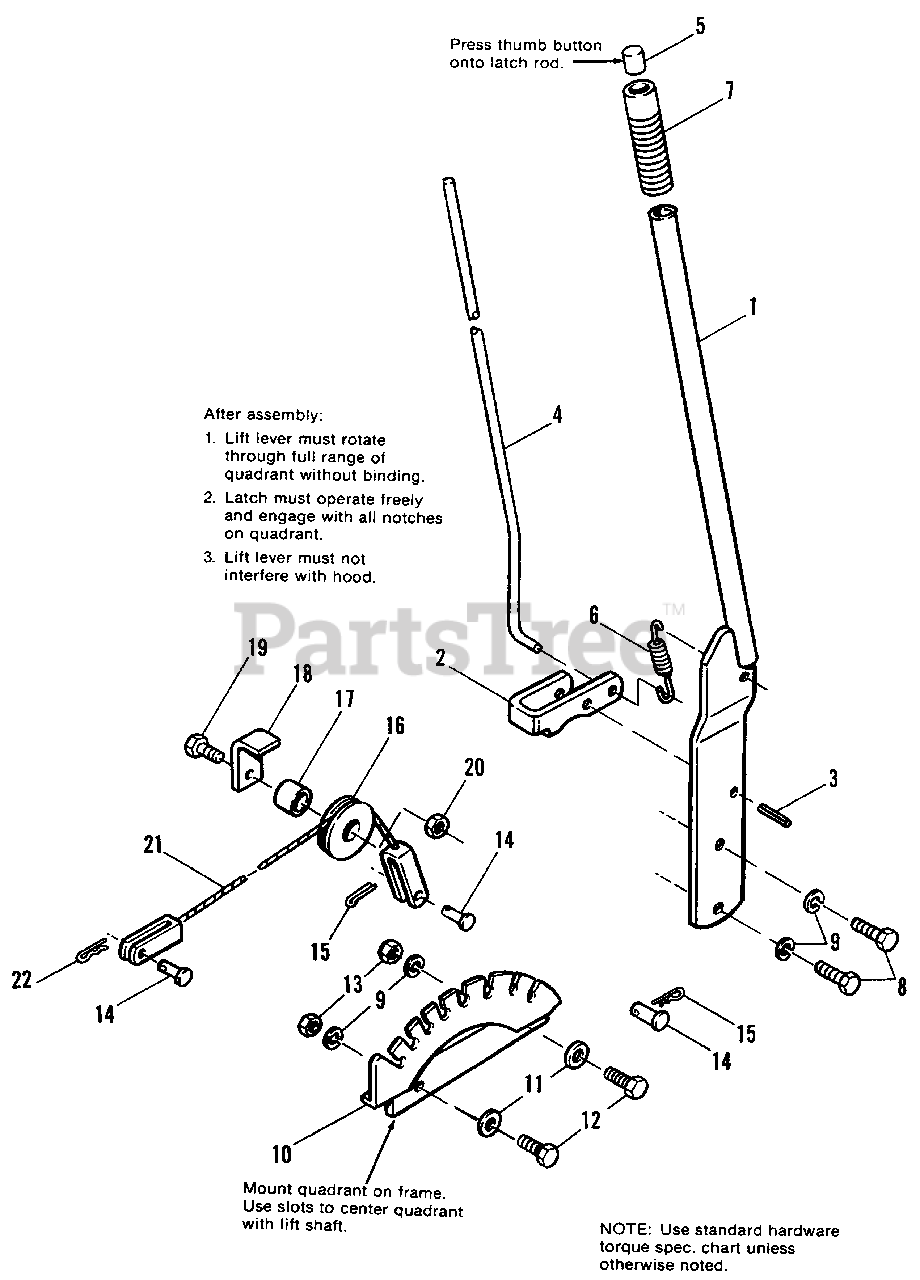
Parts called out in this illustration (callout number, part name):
1	LIFT LEVER ASSEMBLY
2	LATCH, Lift Lever
3	PIN, Spring, 3/8 x 1-1/4
4	ROD, Latch
7	GRIP
8	CAPSCREW, Hex Hd., 3/8-16 x 1
9	LOCKWASHER, 3/8
11	WASHER, 5/16
12	CAPSCREW, Hex Hd., 3/8-16 x 7/8
13	NUT, Hex, Full, 3/8-16
15	CLIP, Spring
18	GUARD, Cable
19	SCREW, Special
20	LOCKNUT, Hex, Jam, 3/8-16
21	LIFT CABLE ASSY.
22	PIN, Cotter, 3/32 x 7/8
